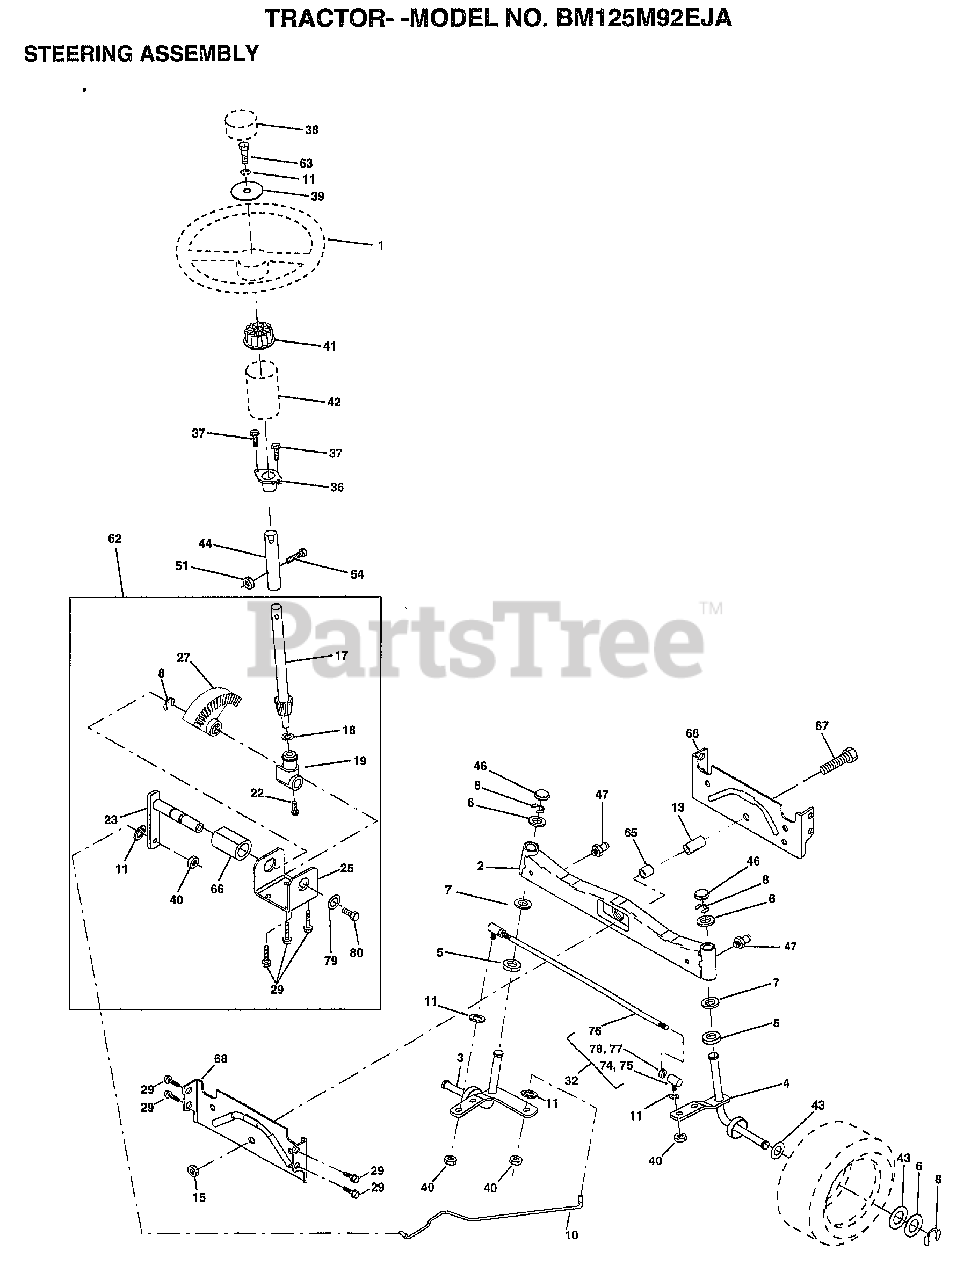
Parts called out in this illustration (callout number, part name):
1	WHEEL STR AYP BLK
3	"SPINDLE ASM,LH"
4	"SPINDLE ASM,RH"
5	WASHER .T
6	WASHER
7	WASHER
8	RING
10	LINK.DRAG
11	LOCKWASHER
13	BEARING.FRT.SPACER.AXLE
15	"NUT-LOC,FLANGE LT"
17	SHAFT ASM STEERIN
18	THRUST WASHER
19	SUPPORT.SHAFT.STEER
22	SCREW.HX.WSH.HD
23	SHAFT.ASM.PITMAN
25	BRKT-STEERING
27	GEAR SECTOR
29	SCREW
32	ROD.ASM.TIE.BALL
36	BUSHING.STEERING
37	"SCREW-TT,10-32 FL"
38	CAP STEER AYP
39	WASHER T
40	GRIPCO NUT
41	ADAPTER LT
42	BOOT.STEER.PL
43	WASHER
44	EXT SHAFT STEERIN
46	CAP
47	ZERK M
51	NUT
54	BOLT
62	KIT.STEER.ASM
63	BOLT
65	SPACER AXLE
66	"BEARING-ARM,PITMA"
67	BOLT
68	BRACE AXLE
74	JOINT.RH
75	JOINT.LH
77	NUT
78	NUT
79	WASHER
80	BOLT.HX.NYLON3/8-16X3/
81	SCREW.HXWSH.3/8
